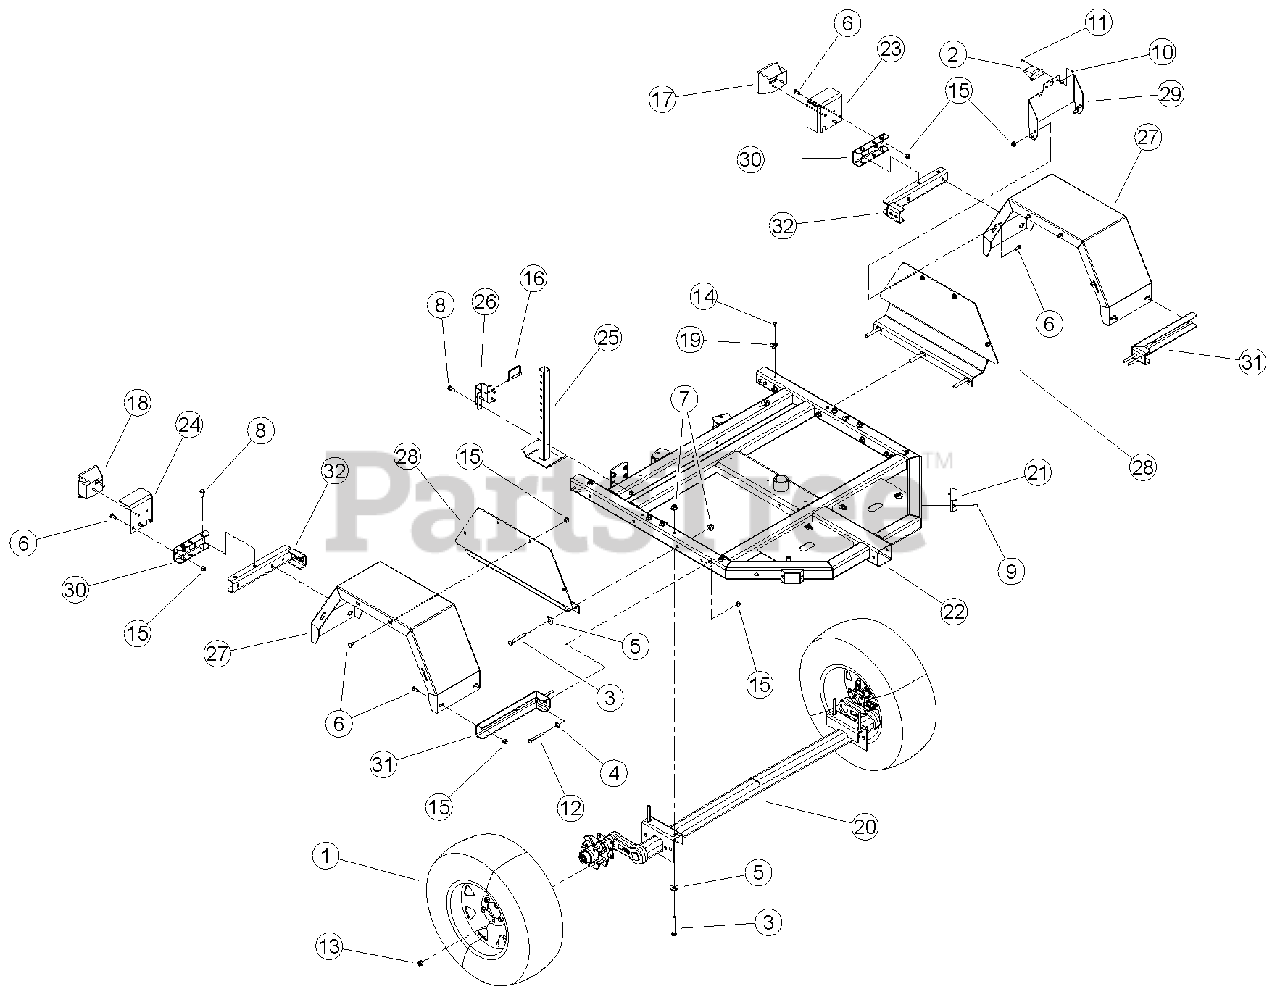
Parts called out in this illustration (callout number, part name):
1	ASSEMBLY, 15 INCH TIRE + WHEEL
2	LIGHT, LICENSE PLATE
3	BOLT, 1/2 X 3-1/2" GR5 HEX HD ZP
4	WASHER, 3/8" FLAT ZP
5	WASHER, 1/2" FLAT ZP
6	BOLT, 3/8 X 1" GR5 CRG NC ZP
7	NUT, 1/2-13 NYLOCK FLANGE
8	BOLT, 3/8 X 1 FLANGE NC
9	SCREW, #10 X 3/4 HEX TAP SC
10	NUT, 10/24 NYLOCK TYPE NM ZP
11	SCREW, MCH 10-24 X 1/2" PAN HD PH ZP
12	BOLT, 3/8 X 3-1/4 HEX HD GR5 ZP
13	NUT, 1/2-20 WHEEL
14	RIVET, AL BLIND 1/4 X 3/4 DOME HEAD
15	NUT, 3/8-16 NYLOCK FLANGE
16	PIN, 3/8 X 2-3/4" SNAP
17	LIGHT, LH TAIL
18	LIGHT, RH TAIL
19	CLAMP, CABLE MOUNT
20	AXLE, TORSION SUSPENSION
21	LIGHT, AMBER MARKER
22	WELDMENT, 8" CHIPPER TRAILER
23	BRACKET, LH TAIL LIGHT
24	BRACKET, RH TAIL LIGHT
25	WELDMENT, REAR STABILIZER
26	GUIDE, TRAILER SUPPORT
27	FENDER, CHIPPER
28	BRACKET, FENDER
29	BRACKET, LICENSE PLATE
30	BRACKET, TAIL LIGHT
31	ANGLE, FENDER GUSSET
32	WELDMENT, FENDER GUSSET
